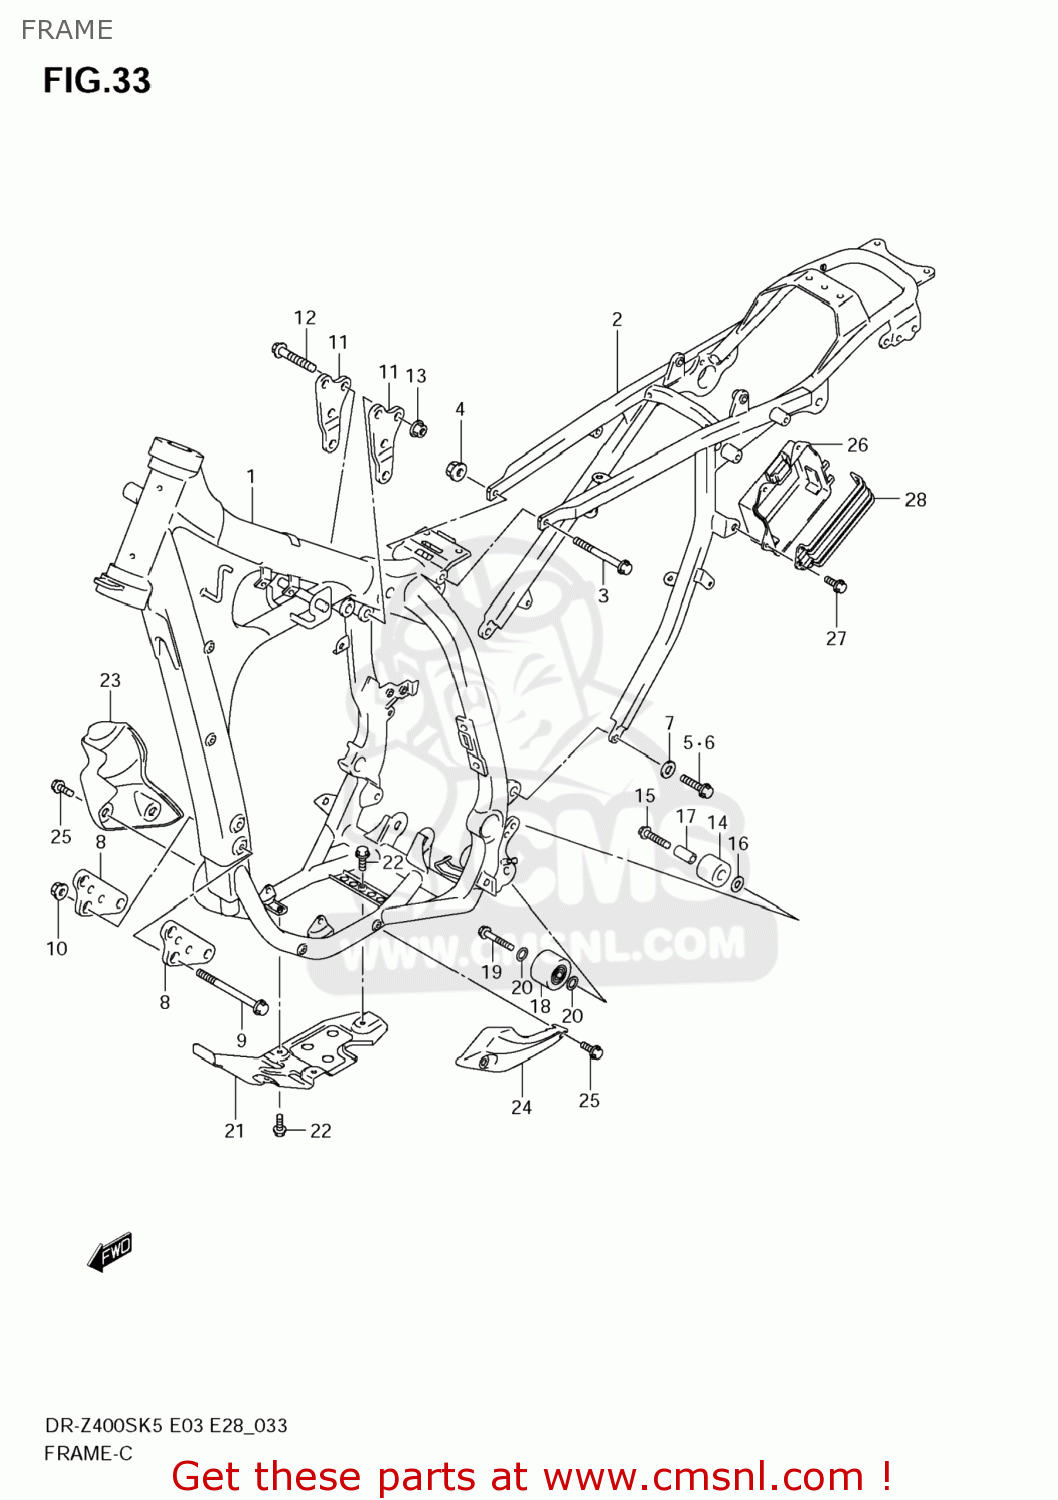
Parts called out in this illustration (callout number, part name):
1	FRAME(GRAY)
2	RAIL, SEAT
3	BOLT(8X115)
4	NUT
5	BOLT(8X18)
6	BOLT(8X20)
7	WASHER(8.5X18X2)
8	PLATE,ENG MTG FR
9	BOLT(8X90)
10	NUT
11	PLATE,HEAD MTG RR
12	BOLT(8X50)
13	NUT
14	ROLLER,CHAIN CONTROL UPR
15	BOLT(8X41)
16	WASHER
17	SPACER(8.6X12.2X26.5)
18	ROLLER,CHAIN
19	BOLT(8X41)
20	SHIM(8X12X1)
21	PROTECTOR,ENGINE
22	BOLT
23	GUARD,WATER PUMP
24	GUARD,MAG COVER
25	BOLT(8X16.5)
26	HOLDER,BATTERY
27	BOLT(6X17.8)
28	BAND,BATTERY HOLDER
